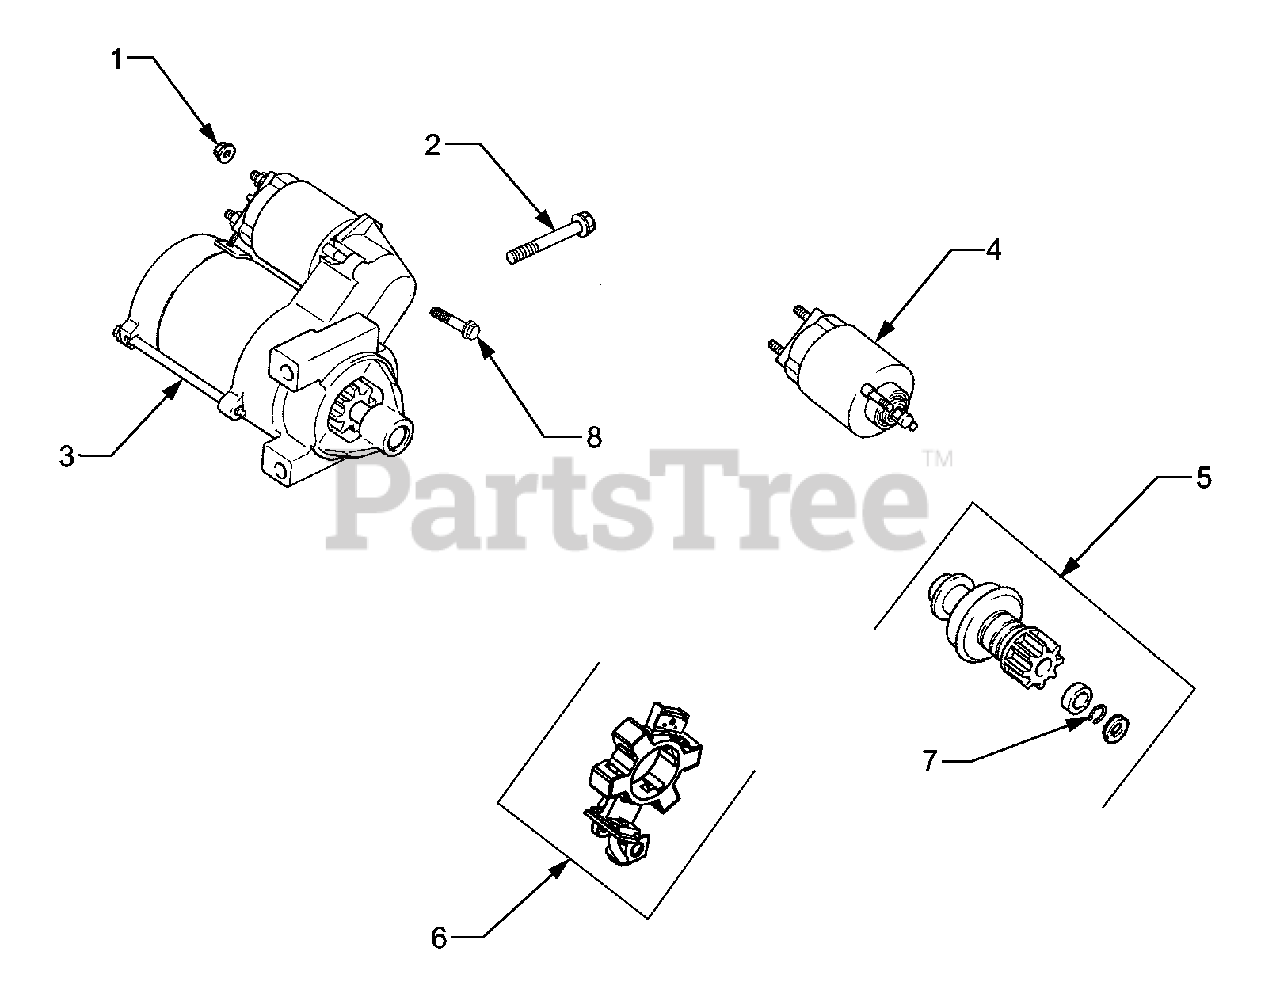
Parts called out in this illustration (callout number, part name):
1	Nut, Hex Flange M8 x 1.25"
2	Screw, Hex Flange M8 x 1.25 x 80
3	Starter, Solenoid Shift Assembly
4	Kit, Solenoid
5	Kit, Pinion Drive
7	Ring, Retainer
8	Screw, External Torx Hd.
